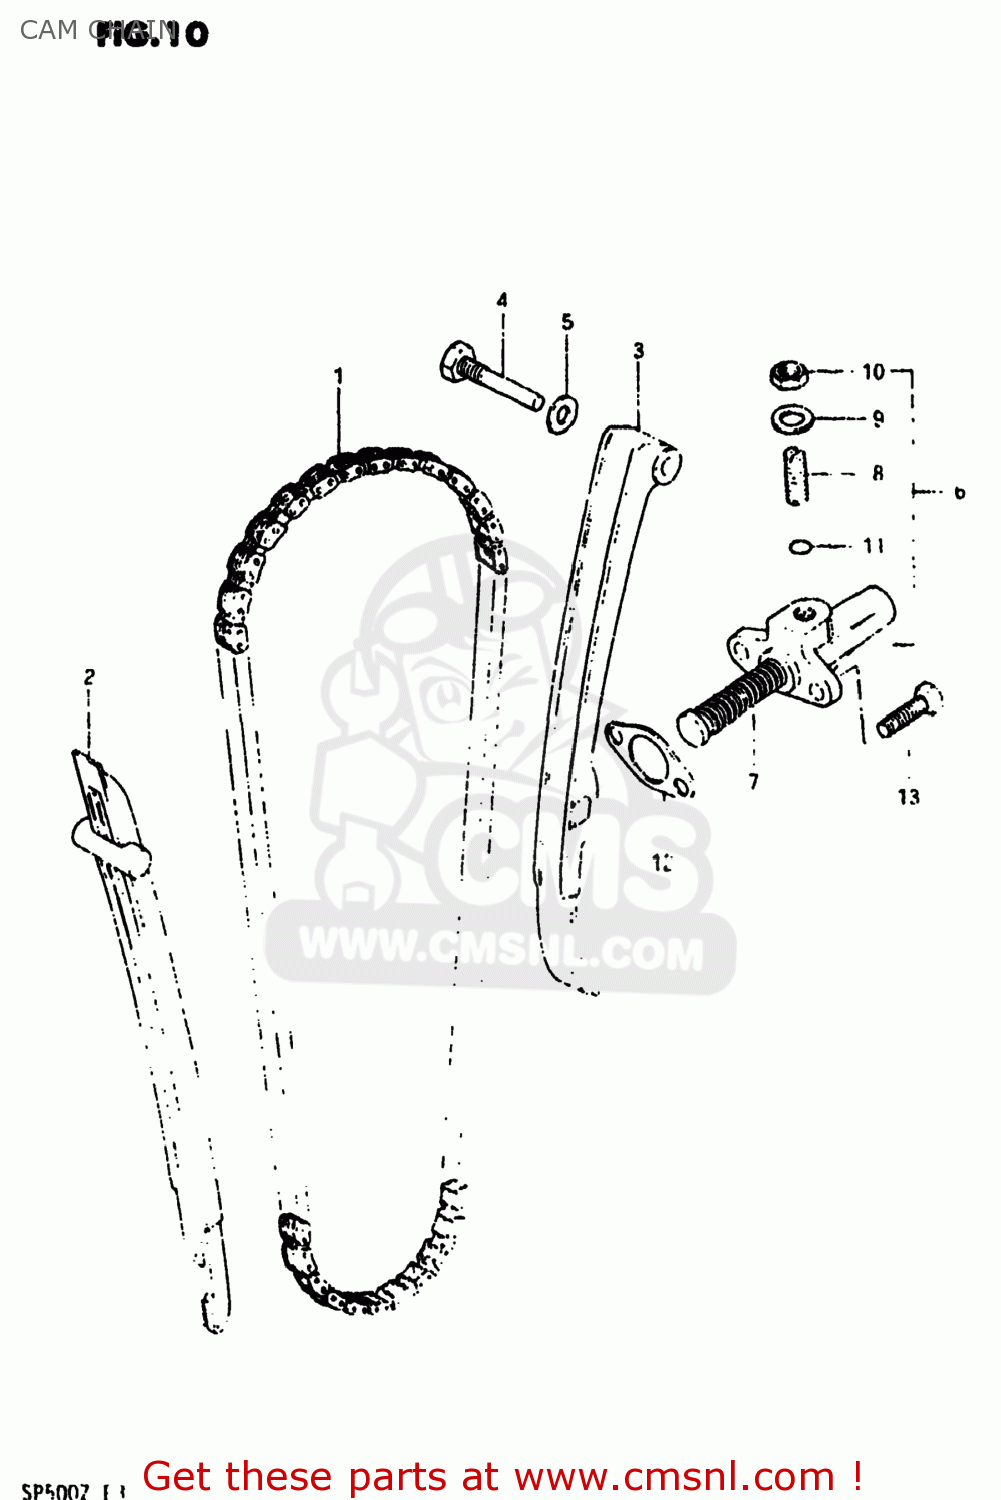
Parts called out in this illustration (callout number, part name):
1	CHAIN,CAMSHAFT DRIVE
2	GUIDE,CAM CHAIN
3	TENSIONER,CAM CHAIN
4	BOLT,CAM CHAIN TENSIONER
5	GASKET 8.2X14X1 (NAS)
6	ADJUSTER ASSEMBLY,TENSIONER
7	SPRING
8	SCREW
9	WASHER
10	NUT
11	O-RING
12	GASKET,TENSIONER ADJUSTER (NAS)
13	BOLT
